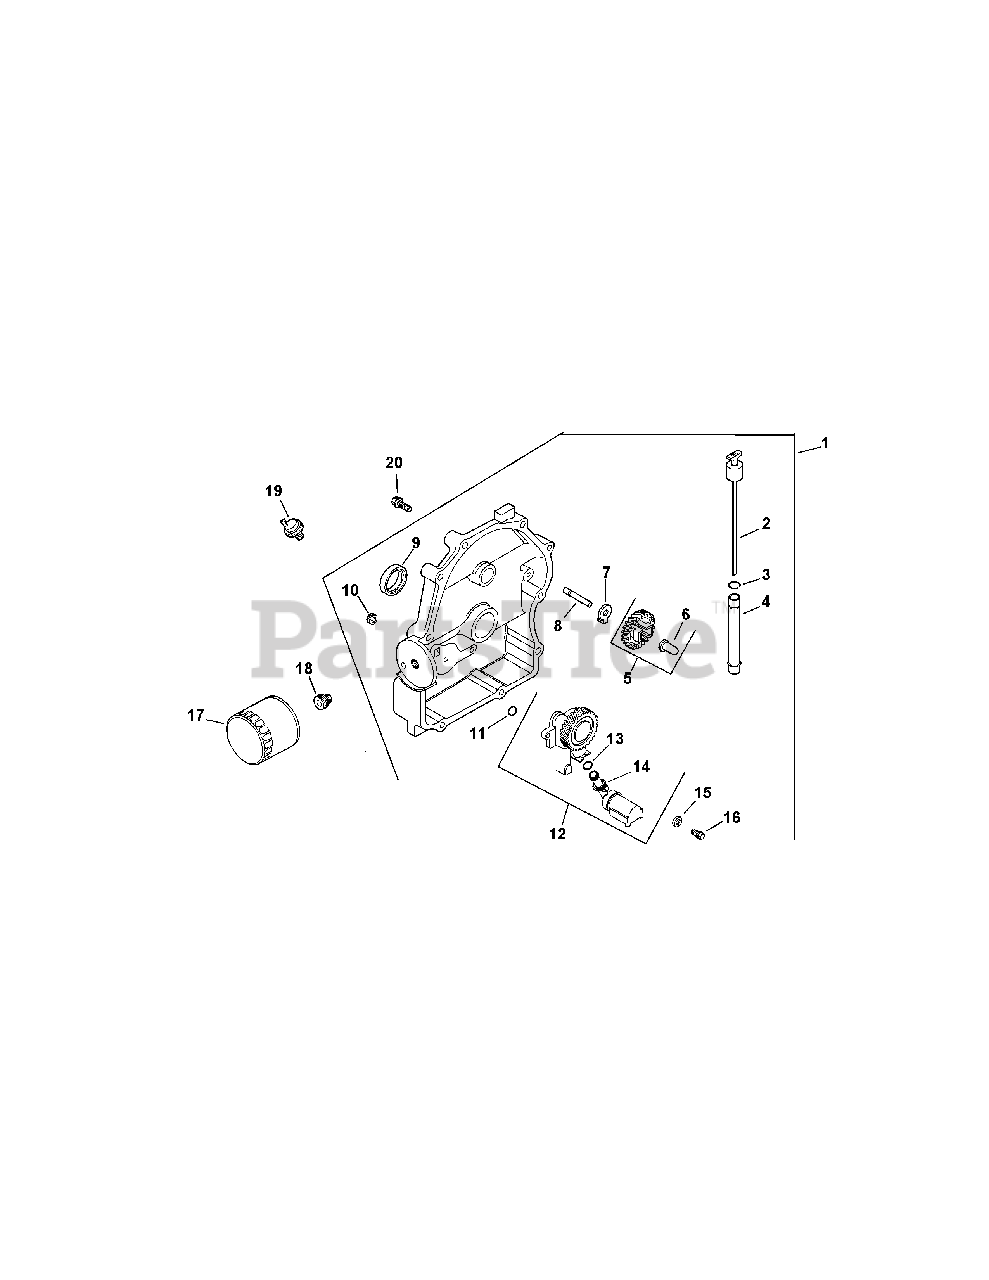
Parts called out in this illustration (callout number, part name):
1	KIT, CLOSURE PLATE ASSEMBLY
4	KIT, OIL FILL TUBE - METAL
5	KIT, GOVERNOR GEAR W/PIN
6	PIN, GOVERNOR REGULATING
8	SHAFT, GOVERNOR GEAR
10	PLUG, CTSK PIPE 1/8''
12	KIT, OIL PUMP ASSEMBLY
13	O-RING, OIL PICK-UP
14	PICK-UP, OIL
15	WASHER, FLAT 6 MM
16	SCREW, FLG THD FRM M6X1.0X25
18	NIPPLE, OIL FILTER
19	SWITCH, OIL PRESSURE
20	SCREW, FLG M8X1.25X45
